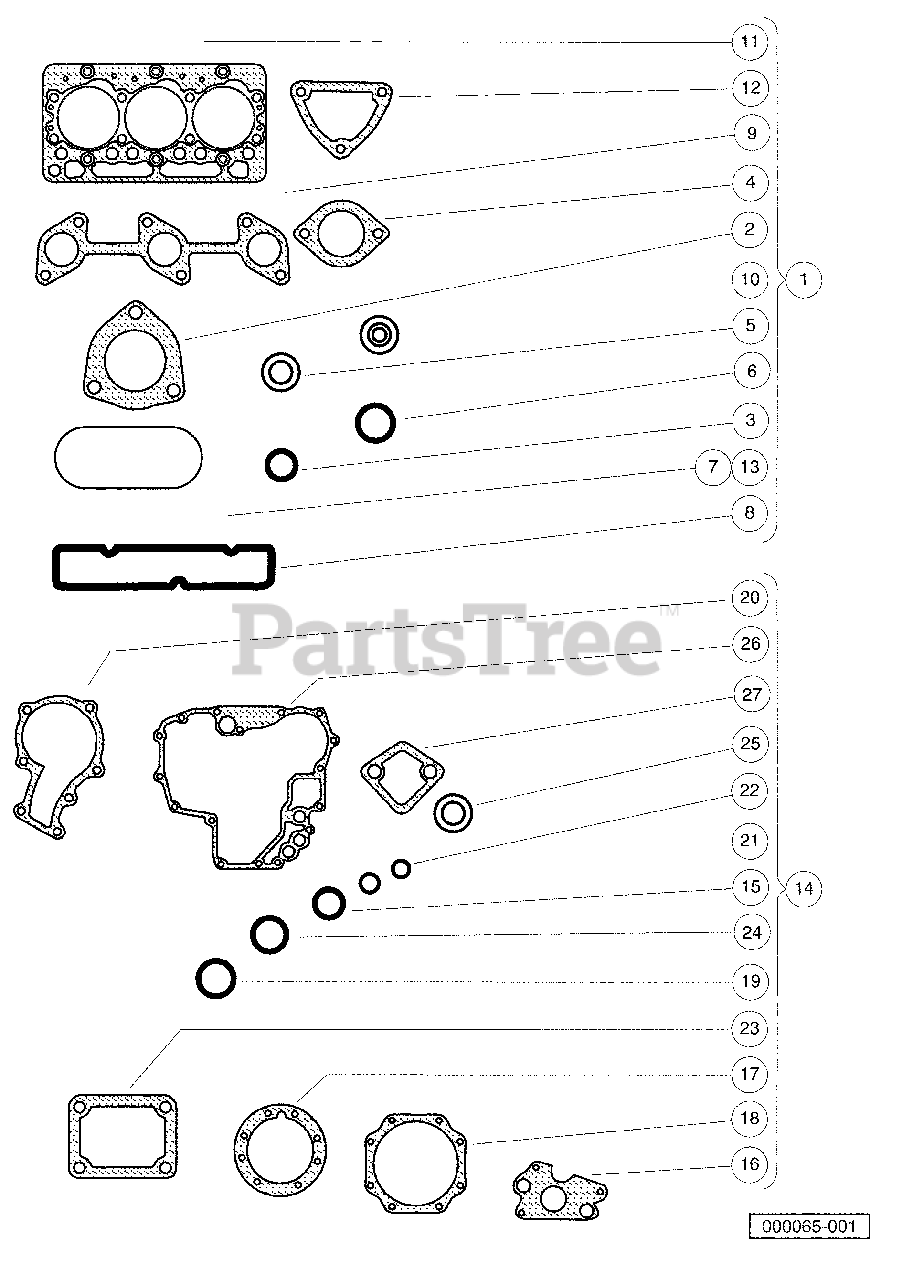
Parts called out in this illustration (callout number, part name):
1	Kit, Gasket Upper, D722
2	Gasket, Exhaust Diesel
3	O Ring, 8 X 7
4	Gasket, Thermostat
5	Gasket, 6 X 10.
6	O Ring, 30 X 36
7	Gasket, Head Cover
8	Gasket, Intake Manifold
9	Gasket, Ex-manifold
10	Seal, Valve Stem
11	Gasket, Cylinder Head
12	Gasket, Water Flange
13	Gasket, Cylinder Head Cover
14	Kit, Gasket Lower, D722
15	O Ring, 18 X 13
16	Gasket, Oil Pump
17	Gasket, Bearing Case
18	Gasket, Cover
19	O Ring, 23 X 26
20	Gasket, Water Pump, D722
21	O Ring, 19 X 16
22	O Ring, 9 X 7
23	Gasket, Control Plate
24	O Ring, 20 X 17
25	Gasket, Idle Apparatus, Rear
26	Gasket, Gearcase, D722
27	Gasket, Fuel Pump, D722
